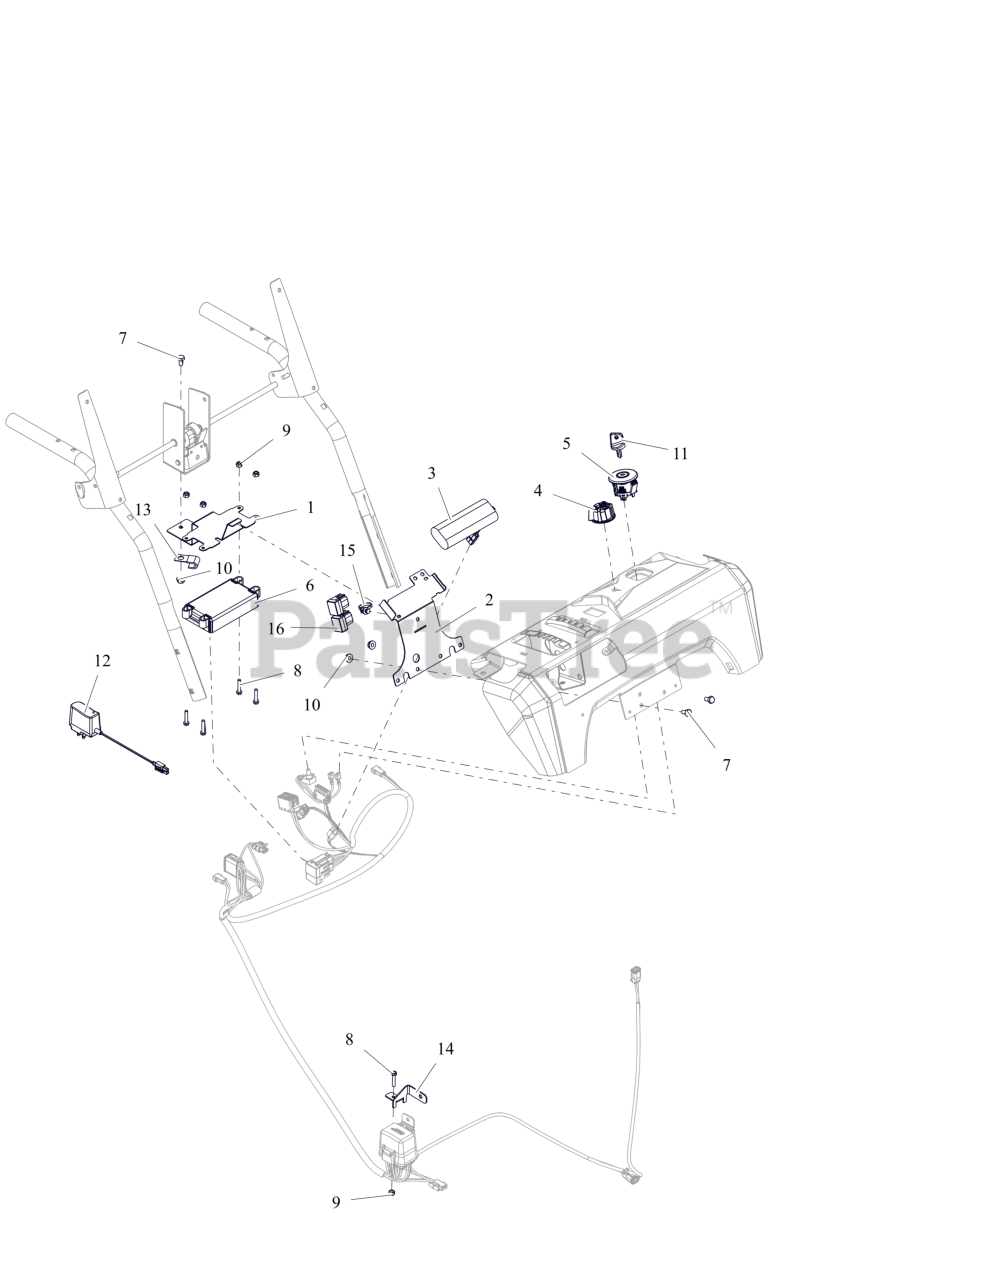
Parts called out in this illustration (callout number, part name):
1	BRACKET, ENGINE EFI-LCT LOWER
2	BRACKET, ENGINE EFI-LCT UPPER
3	BATTERY, SNOW EFI - 7.2V
4	KNOB- CONTROL EFI
5	IGNITION SWITCH ASM - 2 POS
6	ECU SERVICE LCT/CSI - 369CC
7	BLT,HEX .25-20X.50 G5 ZCC
8	BLT, HWH #10-24X1.00 ZCC
9	NUT-LK-NYL #10-24 G2 ZCC
10	NUT-LK-TOP-FLG .250-20 GF ZCC
11	KEY- IGNITION
12	CHARGER, BATTERY - EFI 7.2V
13	J-CLAMP
14	BRKT, MOUNT RECTIFIER
15	CABLE TIE W/ TREE (.25 HOLE)
16	PACK, DIODE
